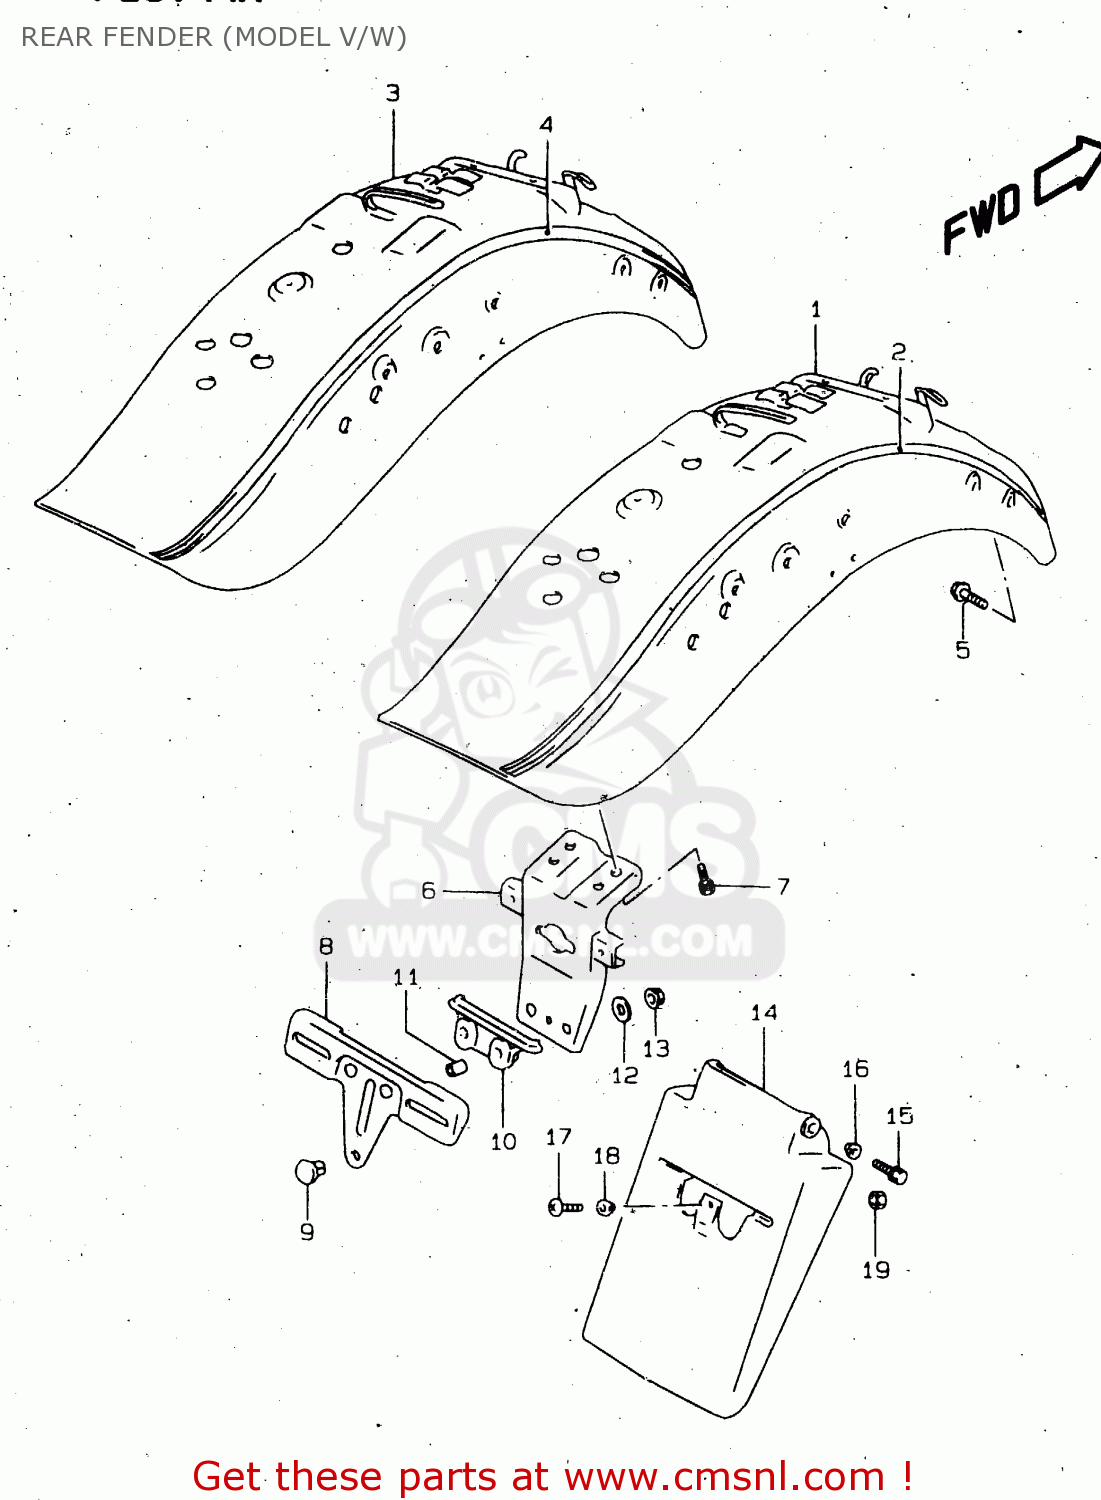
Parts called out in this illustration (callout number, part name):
1	FENDER, REAR
2	TAPE SET,RR FENDER
3	FENDER, REAR
4	TAPE SET,RR FENDER
5	BOLT
6	BRACKET,LICENSE LAMP
7	BOLT
8	PLATE,REAR LICENSE
9	CUSHION
10	CUSHION,RR LICENSE PLATE
11	SPACER(5.5X8X14.3)
12	WASHER(5.5X20X1.2)
13	NUT
14	EXTENSION,RR FENDER
15	BOLT
16	WASHER
17	SCREW
18	WASHER
19	NUT 6MM
